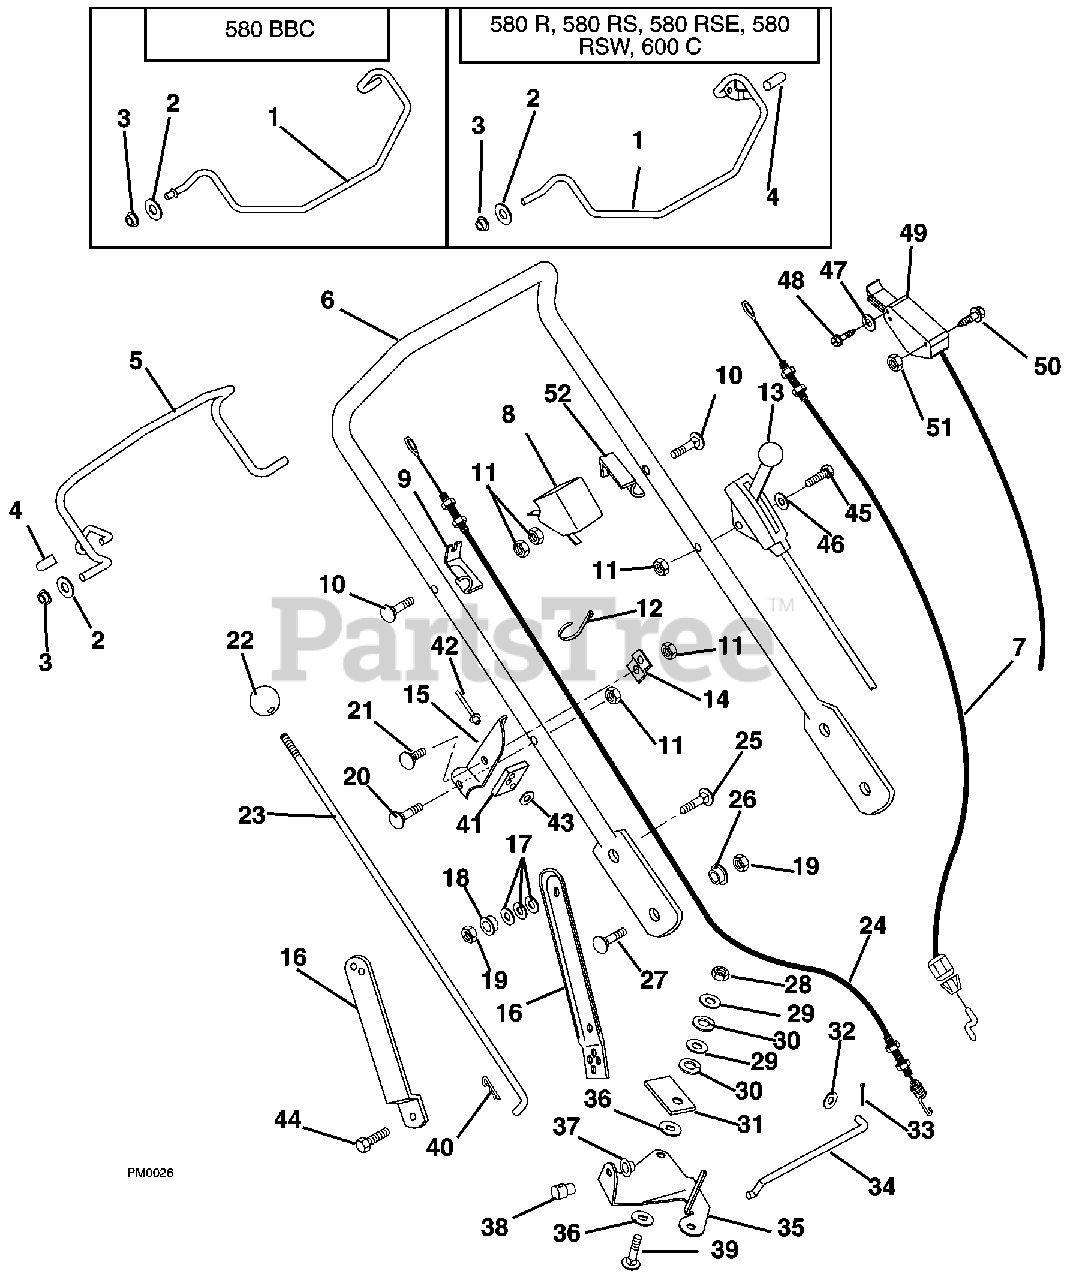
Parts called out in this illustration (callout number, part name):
1	Engine Bail Weldment (580 R, 580 RS, 580 RSE, 580 RSW, 600 C)
2	Washer-Flat-Steel .32 x .44 x .44 x .56 (580 R, 580 RS, 580 RSE, 580 RSW, 600 C)
3	Bushing-Flange .325 x .688 x .560 (580 R, 580 RS, 580 RSE, 580 RSW, 600 C)
4	Cap, Vinyl .25 I.D. (580 R, 580 RS, 580 RSE, 580 RSW, 600 C)
5	Traction Bail (580 RS, 580 RSE, 580 RSW, (580 BBC, 600 C)
7	Engine Control Cable (580 R, 580 RS, 580 RSE, 580 RSW)
8	Switch-Cable Anchor (580 RSE)
9	Cable Anchor-Right Hand
10	Bolt-Round Head Square Neck .25-20 x 1.25 (580 R, 580 RS, 580 RSE, 580 RSW, 600 C)
11	Nut-Locking-Center .25-20 (580 R, 580 RS, 580 RSE, 580 RSW, 600 C)
13	Throttle Cable (600 C)
14	Brace-Speed Control
15	Bracket-Speed Control
16	Link-Handlebar Adjuster Left Hand (580 R, 580 RS, 580 RSE, 580 RSW, 580 BBC)
17	Washer-Bellville Spring (580 R, 580 RS, 580 RSE, 580 RSW, 580 BBC)
18	Bushing-Flange .325 x .50 x .513 x .875 (580 R, 580 RS, 580 RSE, 580 RSW, 580 BBC)
19	Nut-Locking-Center .31-18
20	Bolt-Round Head Square Neck .25-20 x 1.38
21	Bolt-Round Head Square Neck .25-20 x .50 Grade 5
22	Knob (511, 514-516, 522)
23	Rod-Speed Control (580 RS, 580 RSE, 580 RSW, 580 BBC, 600 C)
24	Traction Cable (580 RS, 580 RSE, 580 RSW, 580 BBC, 600 C)
25	Bolt-Round Head Square Neck .31-18 x 1.00 Grade 5 (580 R, 580 RS, 580 RSE, 580 RSW, 580 BBC)
26	Shoulder Spacer
27	Bolt-Round Head Square Neck .31-18 x .75 Grade 5 (580 R, 580 RS, 580 RSE, 580 RSW, 580 BBC)
28	Nut-Locking-Center .38-16 (580 RS, 580 RSE, 580 RSW, 580 BBC, 600 C)
29	Washer-Flat-Steel .406 x .812 x .065 (580 RS, 580 RSE, 580 RSW, 580 BBC, 600 C)
30	Washer-Lock .375 x .115 Heavy (580 RS, 580 RSE, 580 RSW, 580 BBC, 600 C)
31	Pressure Flange (580 RS, 580 RSE, 580 RSW, 580 BBC, 600 C)
32	Washer-Flat-Steel .281 x .620 x .065 (580 RS, 580 RSE, 580 RSW, 580 BBC, 600 C)
33	Pin-Cotter .06 x .50 (580 RS, 580 RSE, 580 RSW, 580 BBC, 600 C)
34	Shift Link (580 RS, 580 RSE, 580 RSW, 580 BBC, 600 C)
35	Bell Crank-Speed Control (580 RS, 580 RSE, 580 RSW, 580 BBC, 600 C)
36	Friction Washer (580 RS, 580 RSE, 580 RSW, 580 BBC, 600 C)
37	Cap, Rod .375 (580 RS, 580 RSE, 580 RSW, 580 BBC, 600 C)
38	Swivel (580 RS, 580 RSE, 580 RSW, 580 BBC, 600 C)
39	Bolt-Round Head Square Neck .38-16 x 1.25 (580 RS, 580 RSE, 580 RSW, 580 BBC, 600 C)
40	Pin-Hair-Internal .08 x .18 x 1.18 (580 RS, 580 RSE, 580 RSW, 580 BBC, 600 C)
41	Support Pad (580 RS, 580 RSE, 580 RSW, 580 BBC, 600 C)
42	Rivet .187 x .575 (580 RS, 580 RSE, 580 RSW, 580 BBC, 600 C)
43	Washer-Flat Steel .219 x .50 x .049 (580 RS, 580 RSE, 580 RSW, 580 BBC, 600 C)
44	Bolt-Hex .31-18 x .75 Grade 5 (600 C)
45	Bolt-Round Head Square Neck .25-20 x 1.75 Grade 5 (600 C)
46	Washer-Flat-Steel .250 x .562 x .049 (600 C)
47	Washer-Flat-Steel .219 x .50 x .049 (580 BBC)
48	Screw-Tapping 10-24 x .50 Hex Washer Head (580 BBC)
49	Control- Blade Brake/Clutch (580 BBC)
50	Screw-Machine 10-24X2.00 Hex Washer Head (580 BBC)
51	Nut-Hex 10-24 (580 BBC)
52	Cable Anchor-Left Hand (580 R, 580 RS, 580 RSW, 600 C)
